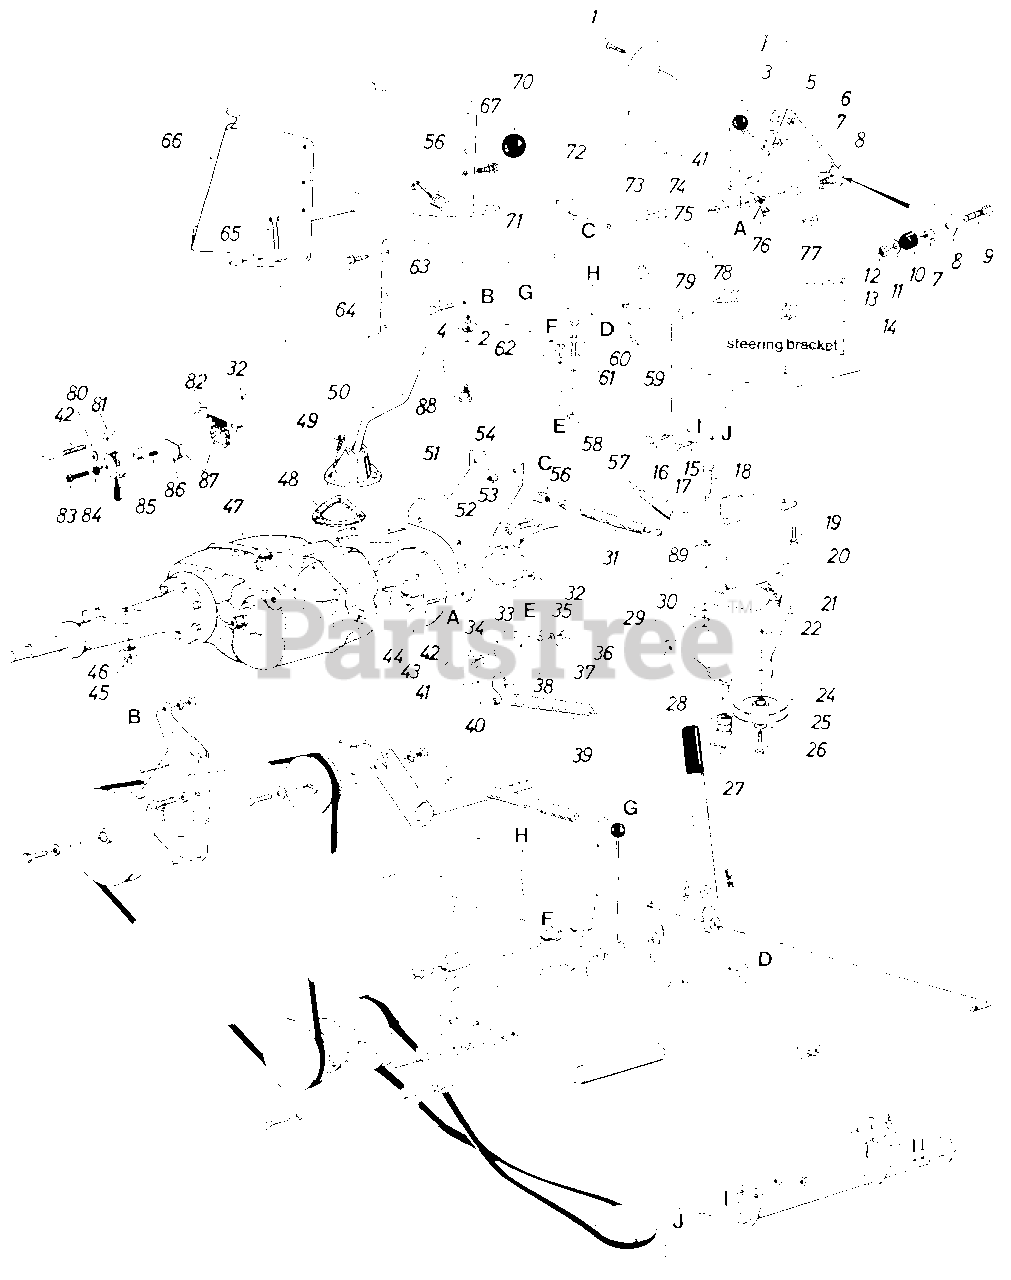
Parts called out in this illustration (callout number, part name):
1	Truss Mach. Scr. 1/4-20 x .50" Lg.
2	Hex Nut 1/4-20 Thd.
3	Knob Blade Clutch
4	L-Wash. 1/4 I.D.
5	Hex Sems Nut 1/4-20 Thd.
6	Push Cap 1/4" Rod
7	Blade Clutch Lever
8	Deck Clutch Control Brkt.
9	Hex Scr. 1/4-20 x 1.25" Lg.
10	Rubber Wash. .330 I.D. x .87
11	Fl-Wash. 1/4" I.D. x .75" O.D. x .057
12	Hex Cent. L-Nut 1/4-20 Thd.
13	Hex Nut 5/16-18 Thd.
14	L-Wash. 5/16" I.D.
15	Hex Bolt 3/8-16 x .62" Lg.*
16	Shld. Bolt 1/2" Dia. x .335 0 Lg. 3/8-16
17	Convoluted Conduit .50 I.D. x 4" Lg.
18	Shld. Bolt 7/16 Dia. x .16" 5/16-18
19	Hex Bolt 5/16-18 x 1.00" Lg.
20	Idler Mtg. Brkt. Deck
21	Idler Brkt. Ass'y.
22	Hex L-Nut 3/8-16 Thd.*
24	4" 'V" Idler Pulley
25	Fl-Wash. 3/8" I.D.
26	Hex Bolt 3/8-16 x 1.25" Lg.
27	Hairpin Cotter 5116" Rod
28	Spacer
29	Hex Nut 5/16-18 Thd.
30	L-Wash. 5/16" Scr.
31	Ext. Spring Brake Rod
32	Hex Cent. L-Nut 3/8-16 Thd.
33	Disc Brake Caliper Ass'y.
34	Shld. Scr. 7116" Dia. x .16" Lg. 5/16-18
35	Parking Brake Cam Mtg. Brkt.
36	Hex Nut 5/16-18 Thd.
37	L-Wash. 5/16" I.D.
38	Hairpin Cotter 5/16" Dia.
39	Ext. Spring Deck Control
40	Deck Control Pivot Brkt.
41	Deck Control Rod
42	Hex Bolt 3/8-16 x 2.50" Lg.*
43	Hub & Disc Ass'y. (For Brake)
44	Hi-Pro Key 3/16 x 314" Lg.
45	Hex Nut 3/8-16 Thd.
46	L-Wash. 3/8" I.D.
47	Transaxle
51	Transaxle Support
52	L-Wash. 318" Scr.
53	Hex Scr. 3/8-16 x .75" Lg.
54	Hex L-Nut 3/8-16 Thd.
56	Ext. Spring Brake Return
57	Ext. Spring Deck Idler Return
58	Hex L-Nut 5/16-18 Thd.
59	Parking Brake Cam Mtg. Brkt.
60	Hex Nut 5/16-18 Thd.
61	Hex Bolt 5/16-18 x 1.5" Lg.
62	Hex Thd. Rolling Scr. 1/4-20 x.50" Lg.
63	Hex Bolt 3/8-16 x .75" Lg.
64	Hex AB-Tap Scr. 5/16 x .75" Lg.
65	Hex Scr. 3/8-16 x 1.50" Lg.
66	Hitch Plate
67	Hex Thd. Rolling Scr. 5/16-24 x .75" Lg.
70	Knob Transaxle
71	Side Panel Upper Frame R.H.
72	Side Panel Upper Frame L.H.
73	Hex Bolt 3/8-16 x .75" Lg.
75	Hex Nut #10-24 Thd.
76	Safety Switch (Deck)
77	Truss Mach. Scr. #10-24 x .50" Lg.
78	Shld. Bolt 7116" Dia. x .16" Lg. 5/16-18
79	Hex Thd. Rolling Scr. 1/4-20 x.50" Lg.
80	Washer
81	Housing with Lever & Pin
82	Anvil
83	Pin, Adjuster
85	Pin, Actuator
86	Backing Plate
87	Lining
88	Shld. Bolt .375" Dia. x .180" Lg. 1/4-20 Thd.
89	Wave Washer
